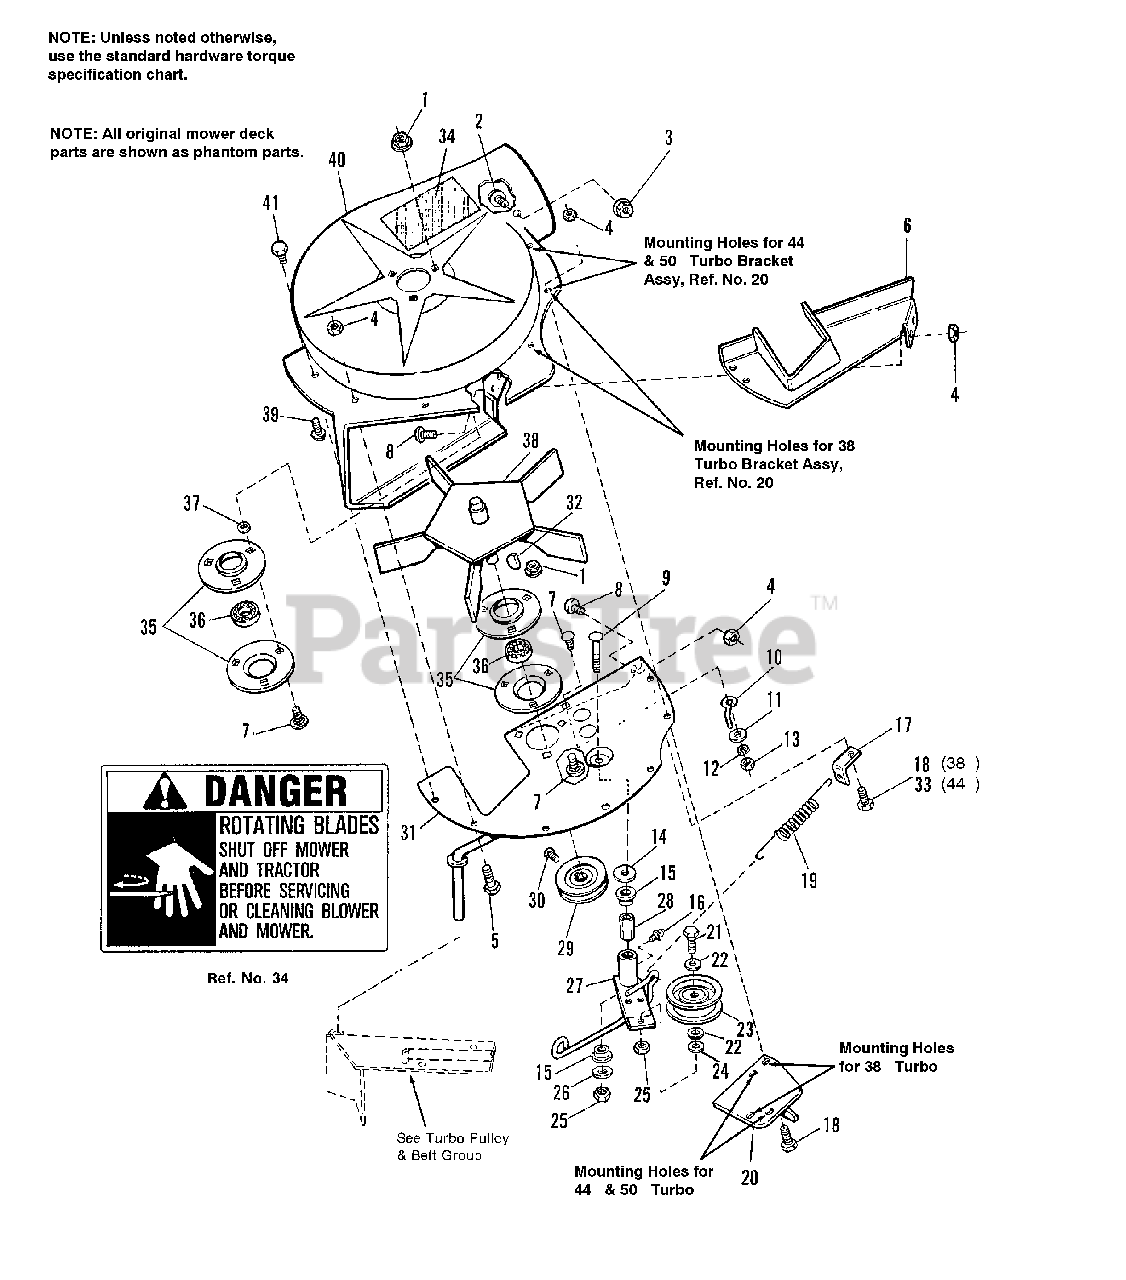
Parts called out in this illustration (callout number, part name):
1	NUT, Flange, Whizlock, 5/16-18
2	CARRIAGE BOLT, 1/4-20 x 5/8
3	NUT, Hex, Nylock, 1/4-20
4	NUT, Hex, Flange Lock, 1/4-20
5	CAPSCREW, Hex, 1/4-20 x 5/8
6	PLATE, Cover
7	CARRIAGE BOLT, 5/16-18 x 3/4
8	SCREW, Truss Hd., 1/4-18 x 5/8
9	CARRIAGE BOLT, 3/8-16 x 2-1/4
11	WASHER, Flat
12	WASHER, Spring Lock, 5/16
13	NUT, Hex, 5/16
14	WASHER, Flat
16	FITTING, Grease
17	BRACKET, Anchor, Spring
18	CAPSCREW, Hex Hd., 1/4-20 x 3/4
19	SPRING, Tension
20	BRACKET ASSY., Turbo
21	CAPSCREW, Hex Hd., 3/8-16 x 1-1/4
22	WASHER, Plain
23	IDLER PULLEY ASSY.
24	WASHER, Flat
25	NUT, Hex, Jam, Center Lock, 3/8-16
26	WASHER, Flat
27	LEVER ASSY, Turbo
29	PULLEY, Driven
30	SETSCREW, Hex, Socket Hd., 5/16-18 x 5/16
31	PLATE ASSY.
32	KEY, Woodruff, Modified
33	CAPSCREW, Hex Hd., 1/4-20 x 7/8
34	DECAL, Danger, Blower
35	BEARING, Retainer
37	PUSH NUT, 3/8
38	FAN ASSY., 5 Blade
39	SCREW, Truss Hd., 1/4-18 x 1/4
40	FAN HOUSING
41	CAPSCREW, Hex, Taptite, 1/4-20 x 1/2
